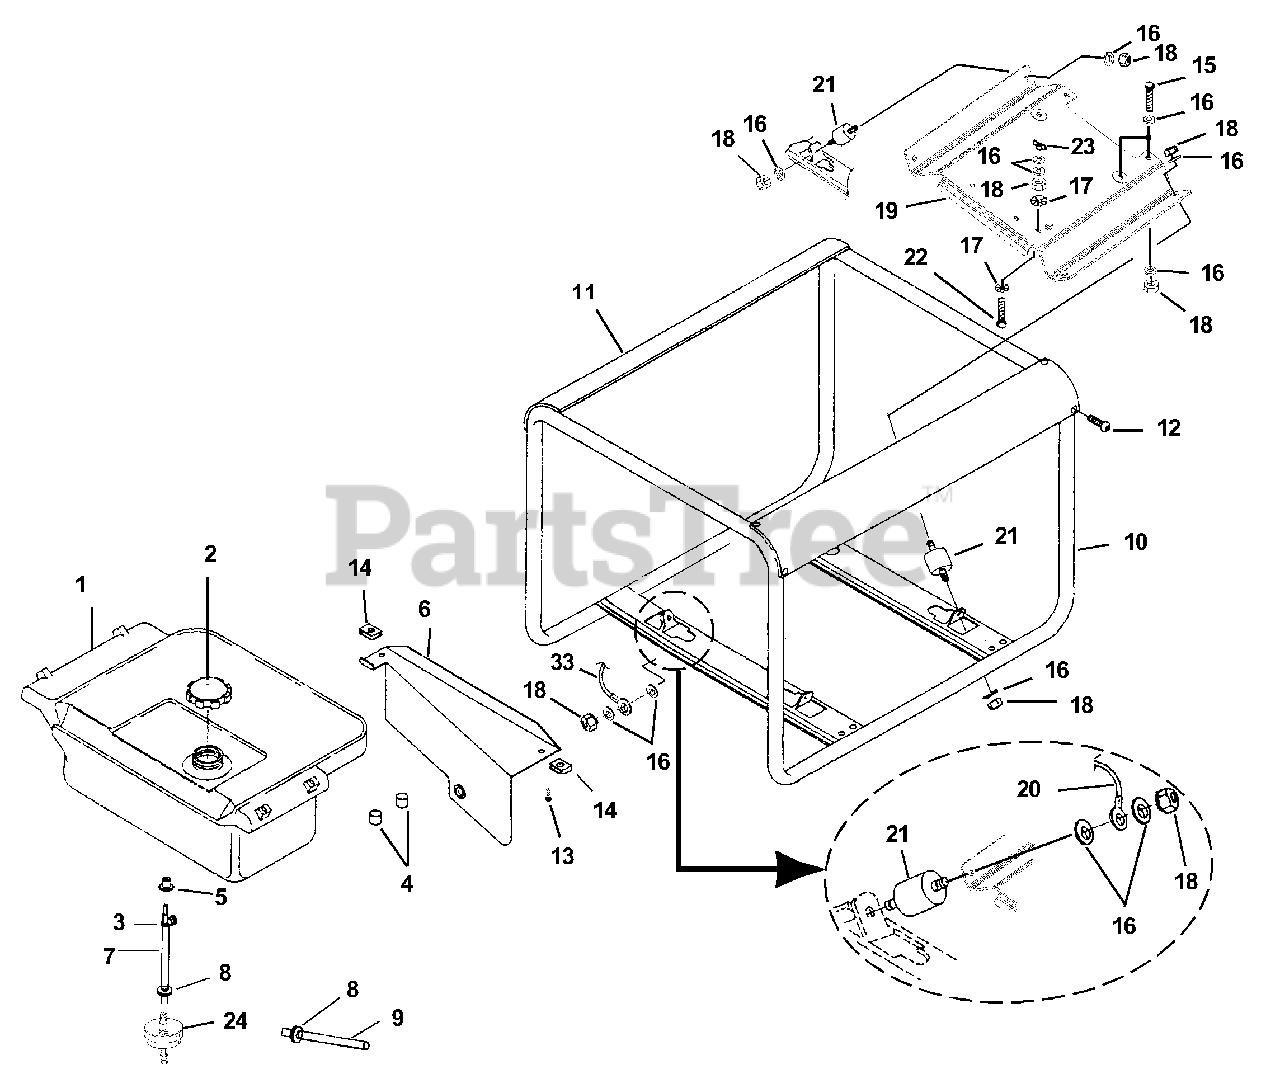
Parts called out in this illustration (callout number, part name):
1	Fuel Tank (5 Gal.)
2	Fuel Cap (2 1/4" dia.)
3	Valve - Fuel
4	Pad - Fuel Tank
5	Bushing
6	Shield - Fuel Tank
7	Fuel Line
8	Clip - Hose
9	Fuel Line to Engine
10	Roll Cage
11	Brace - Tank Support
12	Screw - Torx (10-24 X 1/2")
13	Screw - Pan Hd. (8-32 X 3/8")
14	Nut - Hi Speed
15	Screw - Hex Hd. (5/16-18 X 1 1/2")
16	Washer - Lock (int.)
17	Washer - Lock 3/8" (int/ext.)
18	Nut - Hex (5/16-18)
19	Sub-Frame
20	Ground Strap
21	Isolator
22	Screw - Hex Hd. (5/16-18 X 1 1/2")
23	Nut - Wing
24	Fuel Filter
